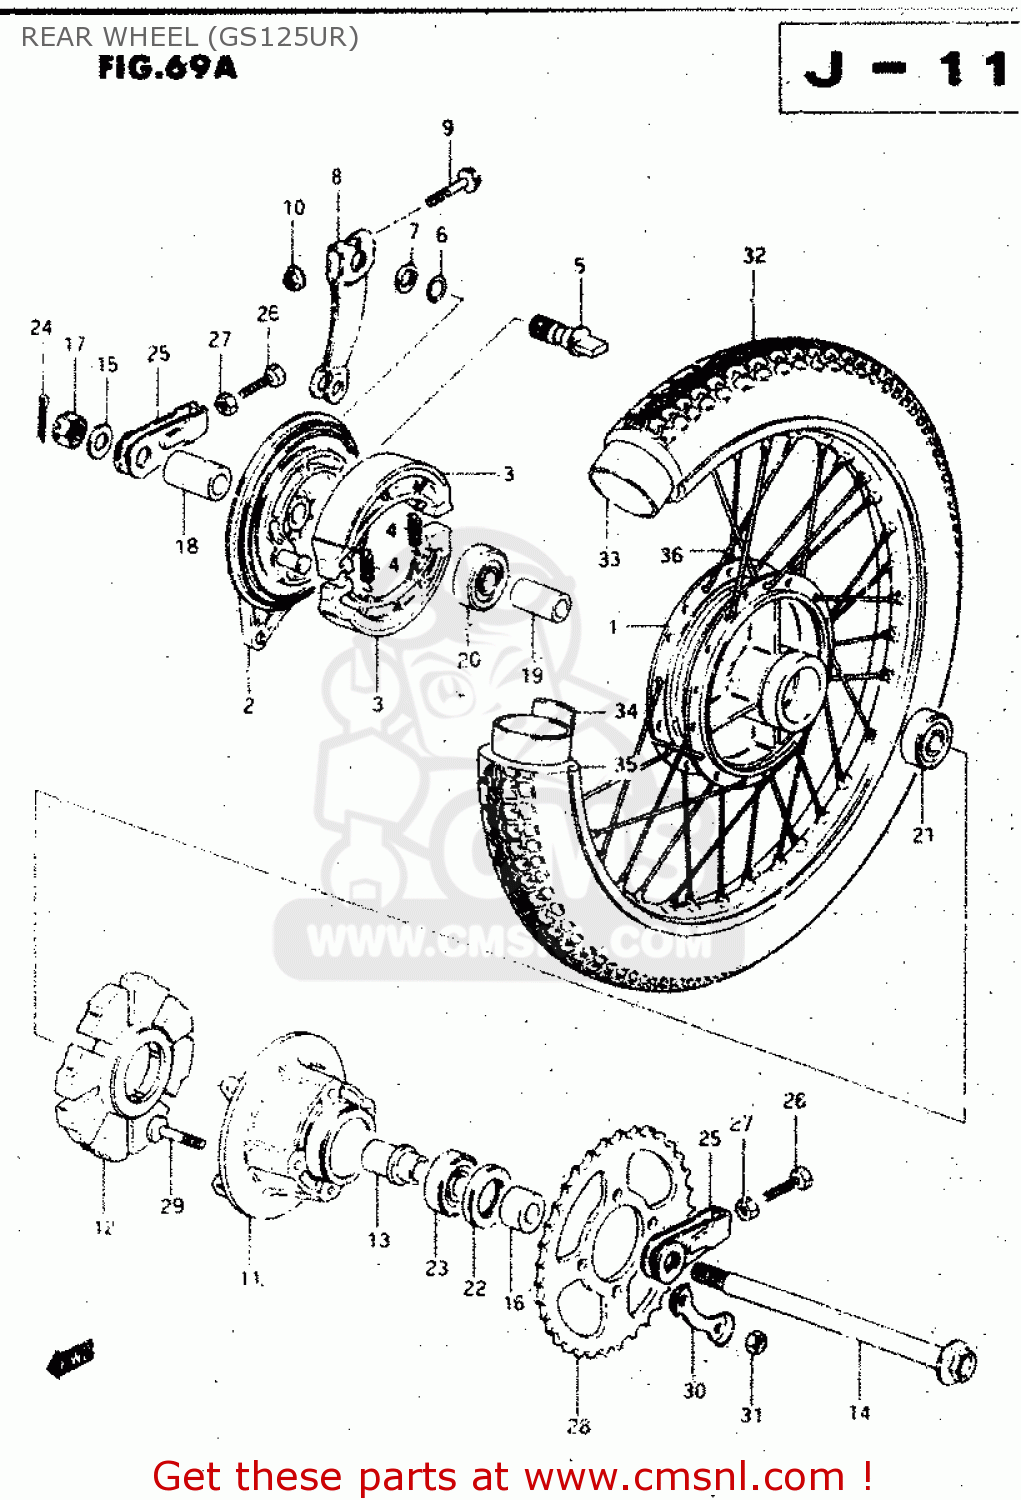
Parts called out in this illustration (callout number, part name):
1	HUB,RR WHEEL
2	PANEL,RR BRAKE ANCHOR
3	SHOE,BRAKE
4	SPRING(L:34)
5	CAM,BRAKE
6	O-RING (D:2.4 ID:13.8)
7	WASHER (14.5X22X1.6)
8	LEVER,RR BRAKE CAM
9	BOLT
10	NUT
11	DRUM,RR SPROCKET MOUNTING
12	ABSORBER ASSY,HUB SHOCK
13	RETAINER,RR SPROCKET DRUM
14	AXLE,RR
15	WASHER
16	SPACER(15X28X19)
17	NUT
18	SPACER(15.2X26X33)
19	SPACER(15.3X21.7X63)
20	BEARING
21	BEARING
22	SEAL,OIL(28X47X7)
23	BEARING(20X47X14)
24	COTTER PIN
25	ADJUSTER,CHAIN
26	BOLT(8X50)
27	NUT
28	SPROCKET,REAR
29	BOLT
30	WASHER
31	NUT
32	TIRE,RR(3.00-18)
33	TUBE,INNER
34	PROTECTOR,INNER TUBE
35	RIM,FR WHEEL 1.60X18
36	SPOKE SET,RR
